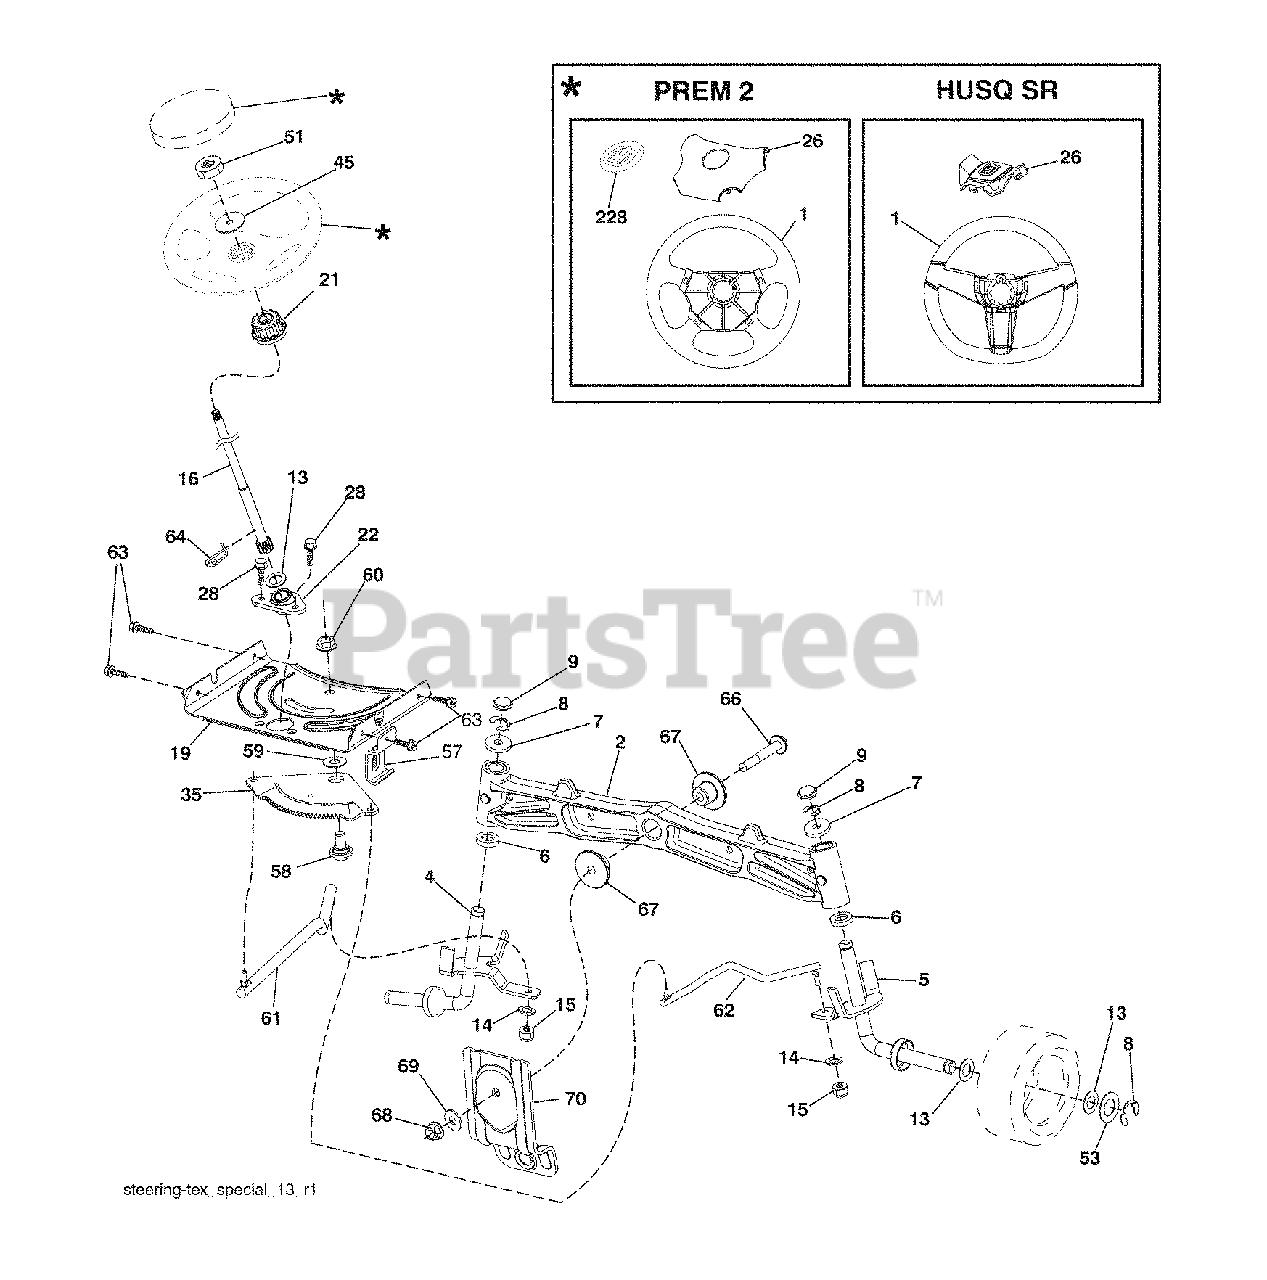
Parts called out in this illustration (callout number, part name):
1	Wheel, Steering
2	Axle Asm., Front
4	Spindle Asm., LH
5	Spindle Asm., RH
6	Bearing, Race Thrust Harden
7	Washer 25/32 x 1-5/8 x 16 Ga.
8	Ring, Clip #T5304-75
9	Cap, Spindle
13	Washer 25/32 x 1-1/4 x 16 Ga.
14	Washer, Lock Hvy Hlcl Spr 3/8
15	Nut, Crown Lock 3/8-24 unf
16	Shaft Steering
19	Plate Steering
21	Adapter, Wheel Steering
22	Bushing, Strg. Blk
26	Insert, Wheel Steering
28	Screw 3/8-16 x 3/4
35	Gear, Sector Plate
45	Washer 9/16 x 2-3/8 x 12 Ga.
51	Nut Hex Jam Toplock 1/2-20 unf
53	Washer Hardened .793 x 1.637 x .060
57	Bracket Upstop
58	Bolt Shoulder Sector Pivot CFM
59	Washer Thrust Sector Steering
60	Nut Flange Lock 5/8-11
61	Draglink, LH
62	Draglink, RH
63	Screw 5/16-18 x 3/4
64	Retainer Clip Spring Steering
66	Bolt Hex Fghd 7/16-14 x 3 Serr
67	Bushing PM Front Axle
68	Nut Lock Flange 7/16-14 Gr. 5
69	Washer 1.5 x .505 x .118
70	Bracket Deck Susp. Front
228	Decal, Wheel Steering
